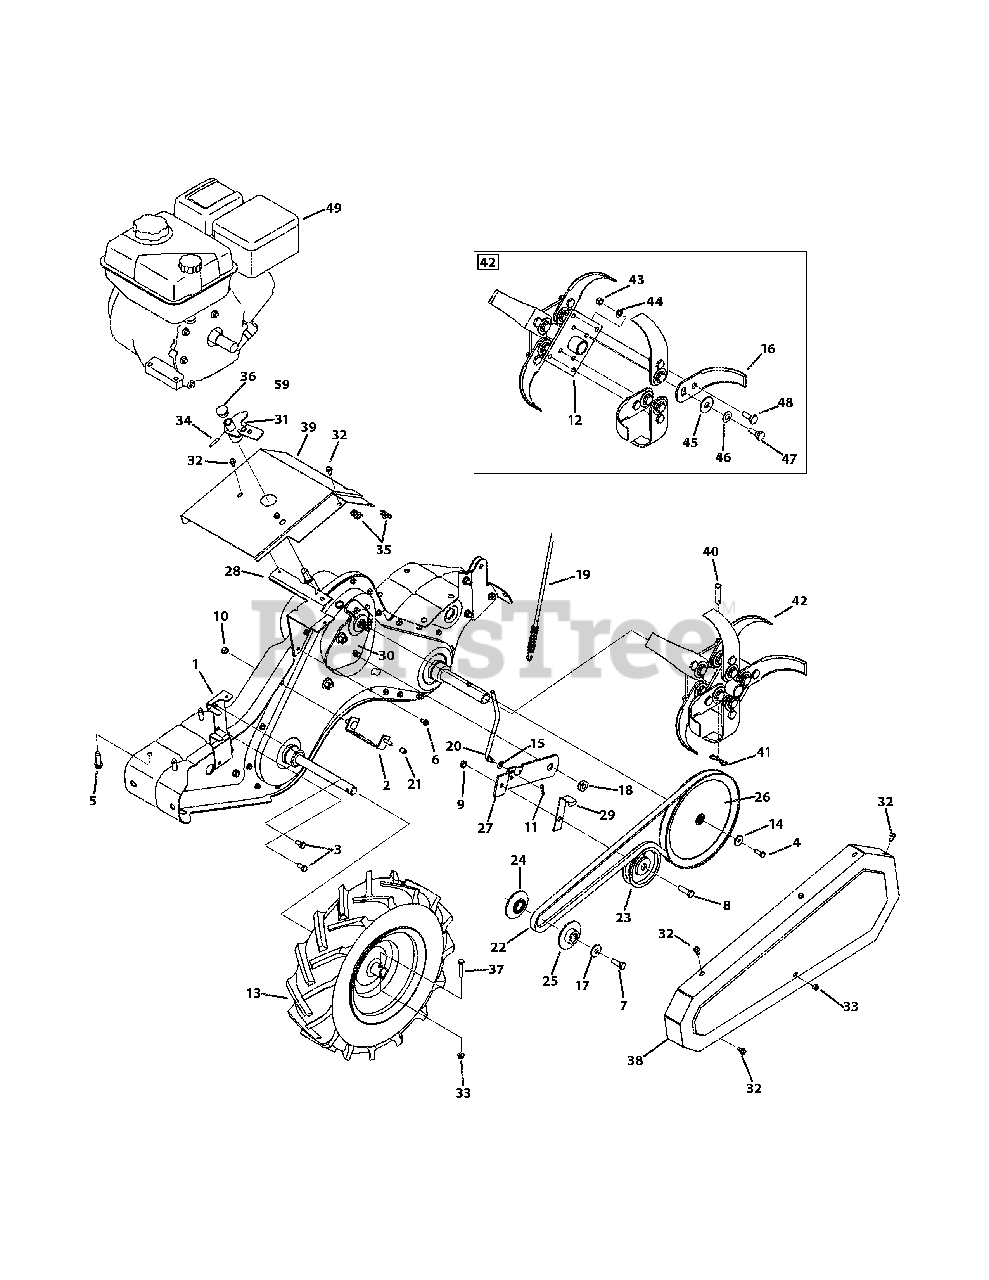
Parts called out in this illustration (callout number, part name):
1	Belt Keeper Assembly Bracket
2	Belt Cover Assembly Bracket
3	Hex Lock Screw, 5/16-24 x .625
4	Hex Screw, 1/4-28 x .625
5	Hex Washer Screw, 3/8-16 x 1.250
6	Hex Washer Screw, 1/4-20 x 0.625
7	Hex Screw, 3/8-24 x 1.00
8	Hex Screw, 3/8-16 x 1.25
9	Jam Lock Nut, 3/8-16
10	Hex Nut, 5/16-18
11	Cotter Pin, .072 x 1.13
12	Tine Adapter Assembly
13	Complete Wheel, 16 x 4.6 x 8
14	Flat Washer, .265 x .938 x .120
15	Spring Washer, .317 x .625 x .020
16	Articulating Tine
17	Bell Washer, .396 x 1.140 x .095
18	Shoulder Nut, 7/16-20
19	Swing Clutch Cable
20	Idler Pulley Rod
21	Spacer, .372 x .260 x .44
22	Belt: 4 x 58.16
23	Flat Idler w/ Flanges 3.75
24	Engine Inner Half Pulley
25	Engine Outer Half Pulley
26	Input Pulley, 4 x 8.594
27	Idler Pulley Bracket
28	Shift Cover Bracket
29	Idler Belt Keeper
30	Positioner Gear Bracket
31	Shift Crank Assembly
32	Hex Washer Screw, 1/4-20 x 0.625
33	Hex Lock Nut, 1/4-20
34	Spirol Pin, 3/16 x 1.00
35	U-Clip Nut, 1/4-20
36	Shift Crank Cap
37	Hex Screw, 1/4-20 x 1.50
38	Belt Cover
39	Shift Cover
40	Clevis Pin, .375 x 1.75
41	Cotter Pin
42	Articulating Tine Assembly
43	Hex Lock Nut, 3/8-24
44	Lock Washer, 3/8
45	Flat Washer, .51 x 1.5 x .07
46	Bell Washer, .525 x 1.00 x .050
47	Shoulder Screw, 3/8-24 x 1/2 x .325
48	Shoulder Screw, 3/8-24 x 1/2 x .180
49	Replacement Engine
